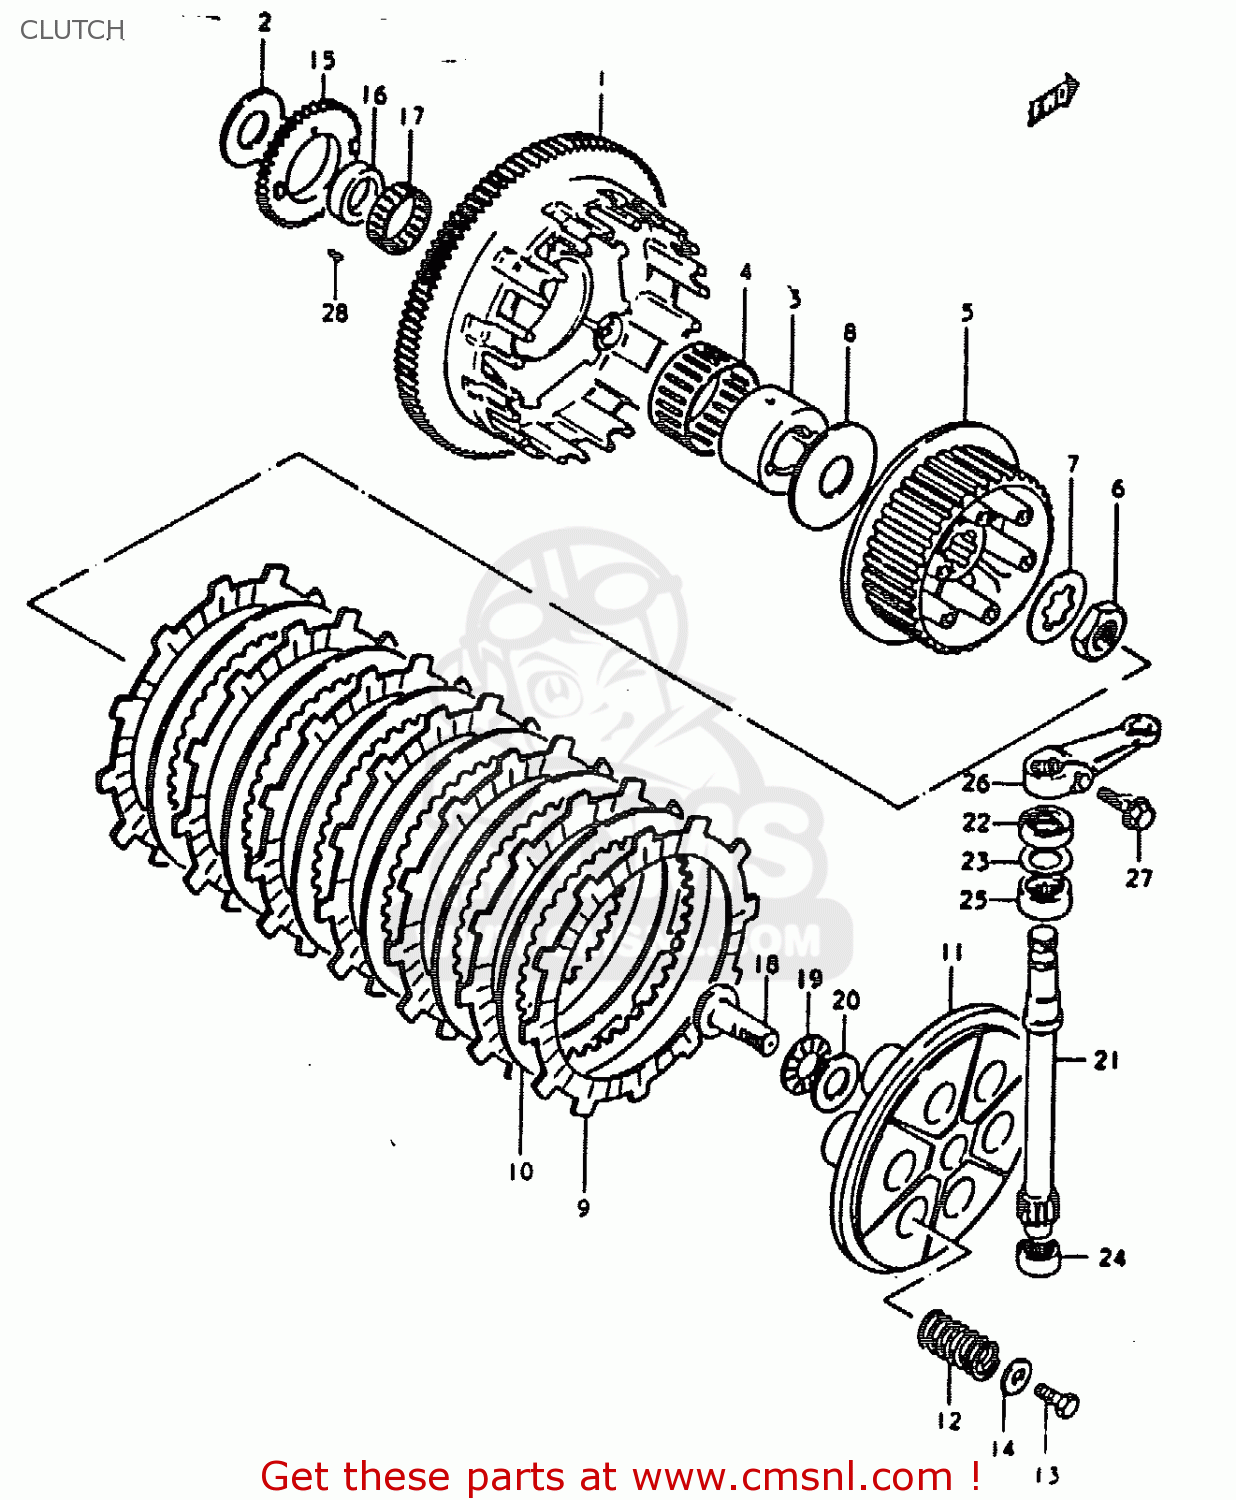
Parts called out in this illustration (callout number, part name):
1	GEAR ASSEMBLY,PRIMARY DRIVE
2	WASHER
3	SPACER,PRIMARY DRIVEN
4	BEARING
5	HUB,CLUTCH SLEEVE
6	NUT
7	WASHER,LOCK
8	WASHER(25X66X3.5)
9	PLATE,CLUTCH DRIVE (MCA)
10	PLATE,CLUTCH DRIVEN (NAS)
11	DISC,CLUTCH PRESSURE
12	SPRING
13	BOLT, UPPER
14	WASHER
15	GEAR,OIL PUMP DRIVE
16	SPACER,OIL PUMP DRIVE GEAR
17	BEARING(36X40X10)
18	RACK,CLUTCH RELEASE
19	BEARING(15X28X2)
20	WASHER
21	PINION,CLUTCH RELEASE
22	OIL SEAL
23	WASHER (14.2X22X1)
24	BEARING(12X19X12)
25	BEARING(15X22X12)
26	ARM,CLUTCH RELEASE
27	BOLT
28	CUSHION,PRIMARY DRIVEN GEAR
